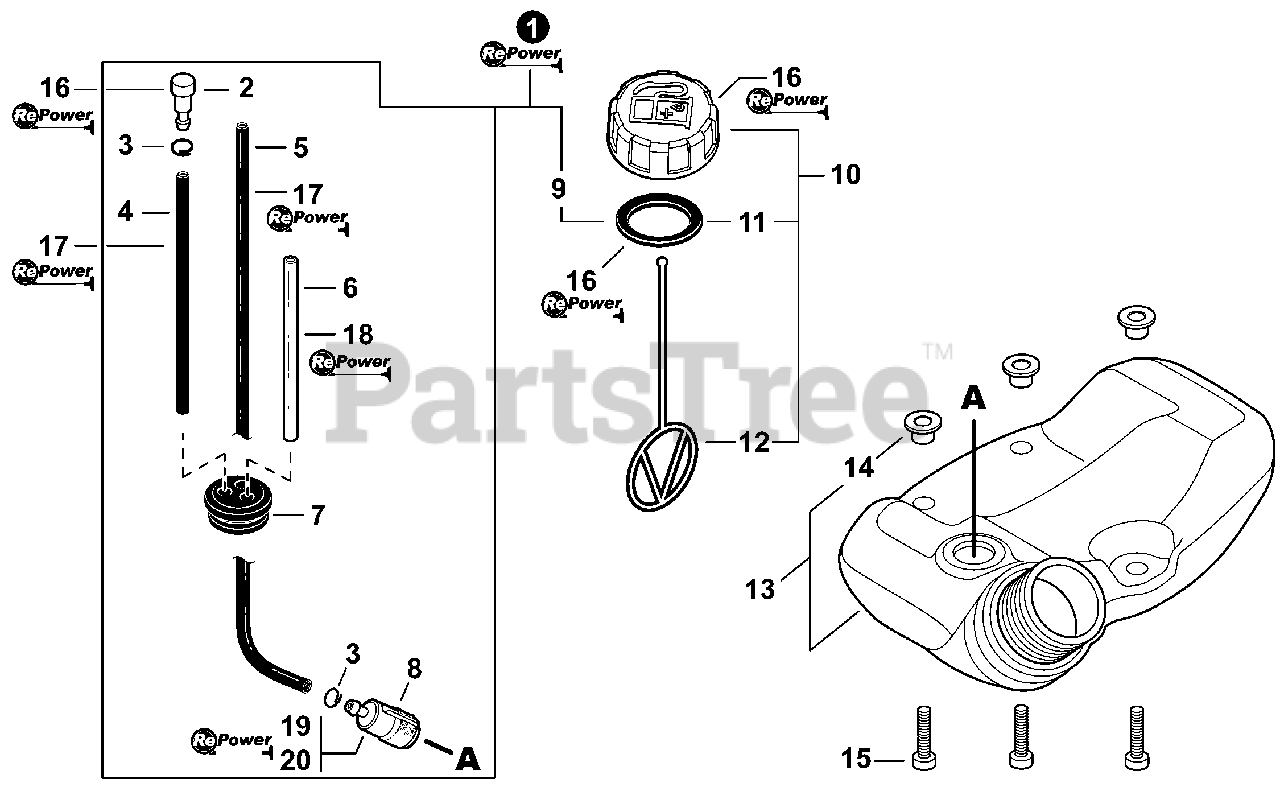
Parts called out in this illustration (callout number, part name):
1	FUEL SYSTEM KIT
2	VENT ASSY
3	CLIP 6 MM
4	PIPE, FUEL 3×5×90 BLACK
5	PIPE, FUEL 3×5×210 BLACK
6	PIPE, FUEL 3×6×80 CLEAR
7	GROMMET, FUEL
8	FILTER, FUEL
9	GASKET, FUEL CAP
10	CAP ASSY, FUEL
11	GASKET, FUEL CAP
12	CONNECTOR, CAP L= 123
13	TANK ASSY, FUEL
14	COLLAR 5
15	BOLT, TORX 5×20
16	CAP/VENT KIT - REPOWER
17	BULK PIPE - 3×5 MM BLACK (4 PIECES×2 M)
18	BULK PIPE - 3×6 MM CLEAR (4 PIECES×2 M)
19	TUNE-UP KIT - REPOWER
20	FILTER KIT - REPOWER
